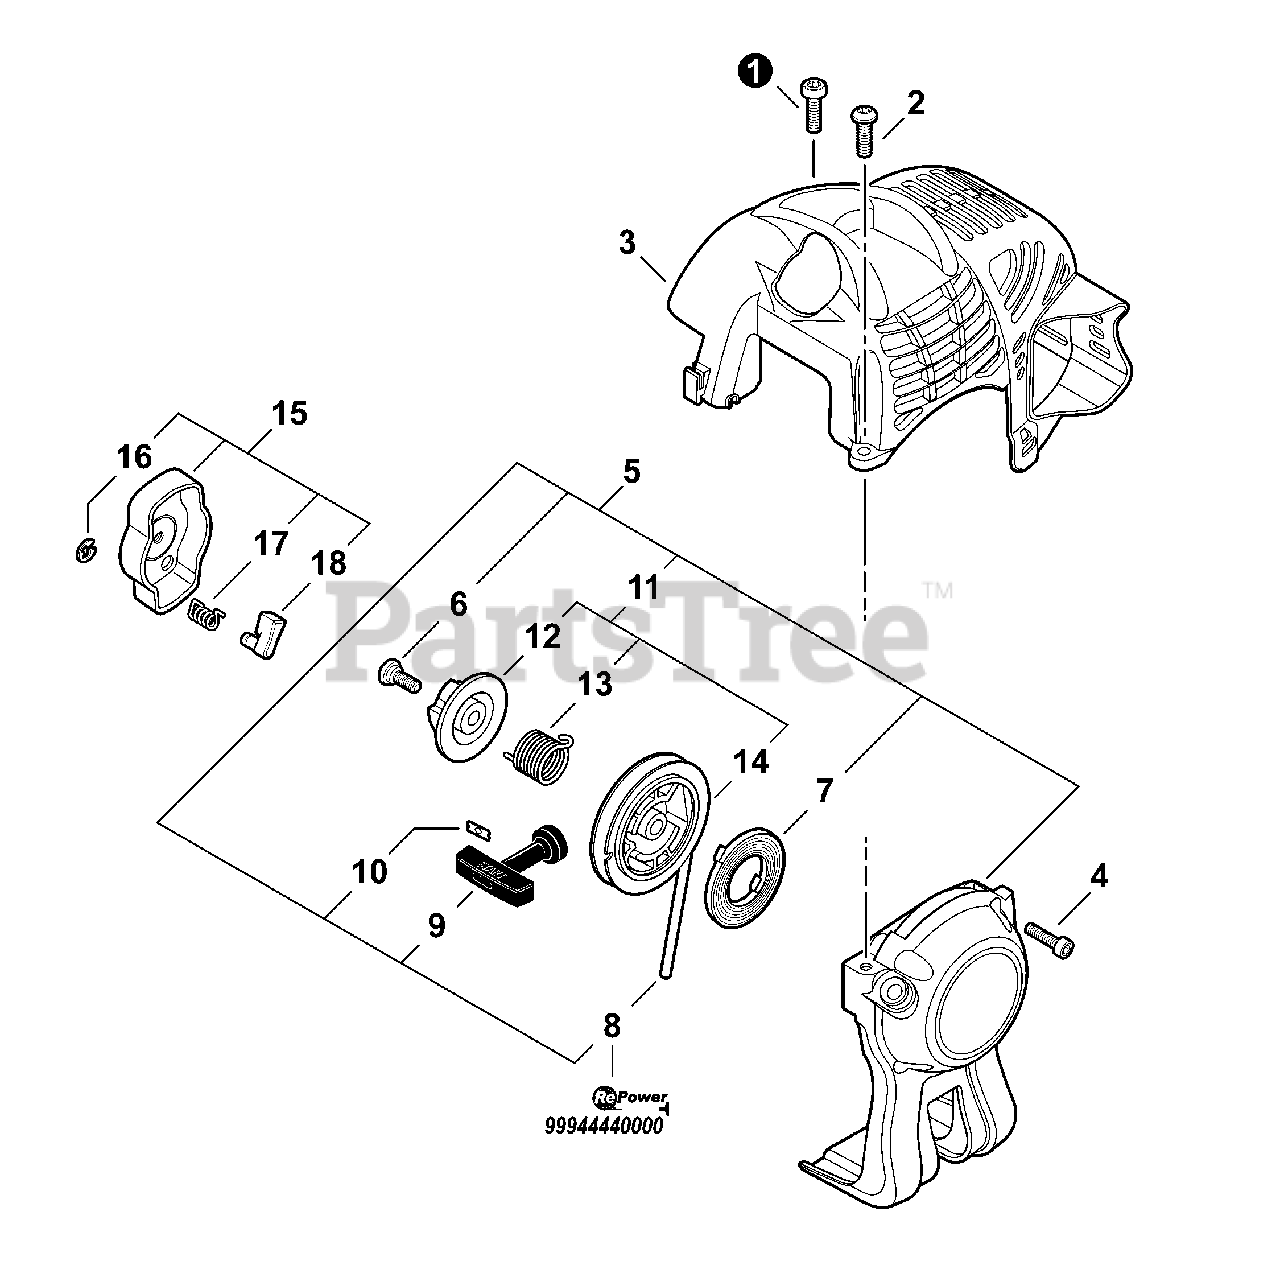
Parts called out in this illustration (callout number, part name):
1	SCREW - 5X16
2	SCREW - 5X16
3	COVER, ENGINE
4	SCREW - 4X16
5	STARTER ASSY
6	SCREW
7	SPRING, REWIND
8	ROPE, STARTER - 3X700
9	GRIP, STARTER
10	RETAINER, ROPE
11	ROPE REEL KIT
12	PLATE, CAM
13	SPRING, DAMPER
14	REEL, ROPE
15	STARTER PAWL ASSY
16	RING, RETAINING -4
17	SPRING, RETURN
